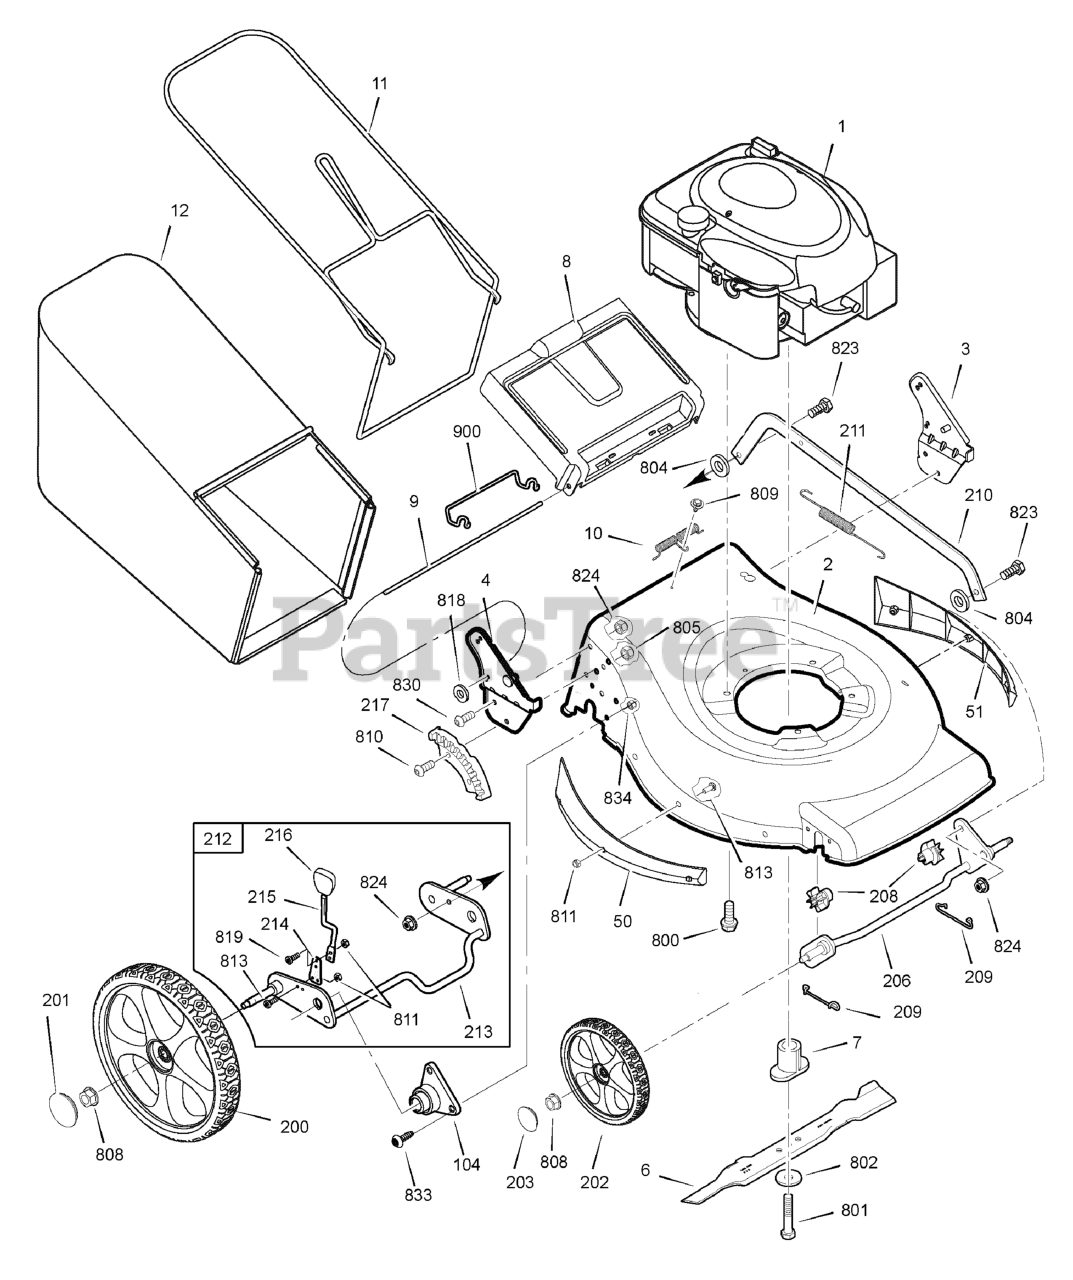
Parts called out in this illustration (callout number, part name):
1	* ENGINE
2	MOWER HOUSING
3	BRACKET ASSEMBLY, Left Handle
4	BRACKET ASSEMBLY, Right Handle
6	BLADE, 16 in
7	BLADE ADAPTER ASSEMBLY
8	DOOR, Rear
9	ROD, Rear Door
10	SPRING, Torsion Rear Door
11	FRAME ASSEMBLY
12	BAG ASSEMBLY
50	SIDE GUARD, Right
51	SIDE GUARD, Left
104	SLEEVE ASSEMBLY, Rear Axle
200	WHEEL, Rear
201	HUBCAP, Rear
202	WHEEL, Front
203	HUBCAP, Front
206	CROSSBAR ASSEMBLY, Front
208	BUSHING, Front Crossbar
209	SPRING, Clip Crossbar
210	LINK, Single Lever
211	SPRING, Extension
212	CROSSBAR ASSEMBLY, Rear
213	REAR CROSSBAR
214	SPRING, Adjuster
215	LEVER, Height Adjustment
216	KNOB, Adjuster
217	BRACKET, Height Adjuster
800	SCREW, Hex Head, 3/8-16 x 1
801	BOLT, Blade, 3/8-24 x 2
802	WASHER, Belleville
804	WASHER, 5/8
805	NUT, Nylock, M8 x 1-1/4
808	NUT, Flange, 3/8-16
809	NUT, Flange, 3/8-16
810	BOLT, Hex Key Head
811	NUT, Nylock
813	SCREW, Torx Head, M5 x .8 x 14mm
818	NUT, Speed
819	SCREW, Torx Head, M5 x .8 x 12.5mm
823	BOLT, Shoulder, 5/16-18 x 1
824	Nut, Flange, 5/16-18
830	SCREW , 5/16-18 x 3/4
833	SCREW, Torx, 1/4-20 x 5/8
834	NUT, Flange Lock, 1/4-20
900	SPRING CLIP, Rear Door
1000	CRADLE
1001	MANUAL KIT
